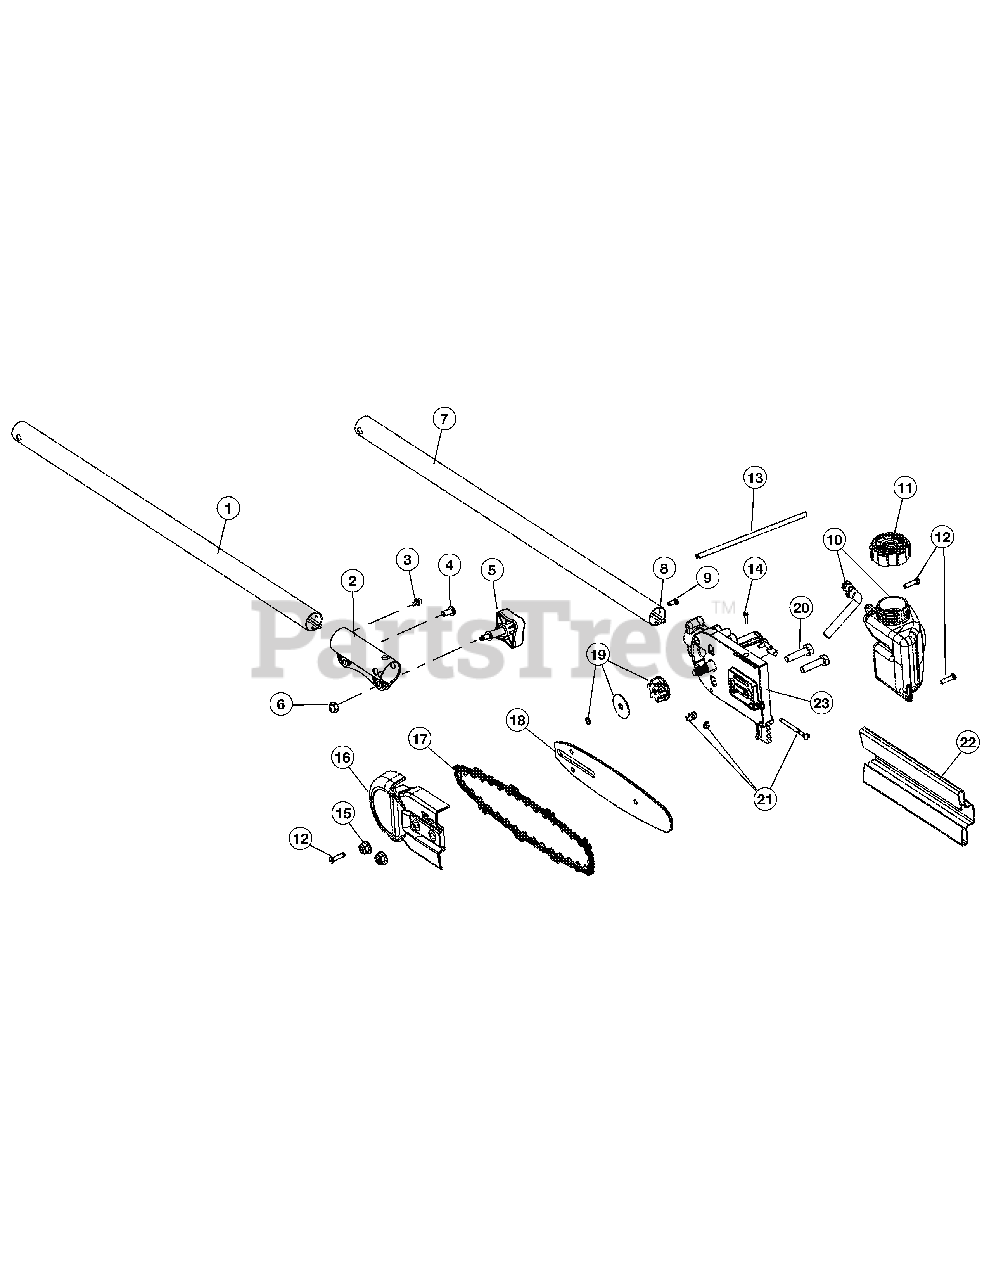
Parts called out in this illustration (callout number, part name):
1	Extension Boom
2	Split Boom Coupler (includes 3-6)
5	Adjustment Knob
6	Knob Retaining Nut
7	Drive Shaft Housing Assembly (includes 8)
8	Flexible Drive Shaft
9	Screw
10	Oil Tank Assembly
11	Fuel Cap Assembly
12	Screw
14	Screw
15	Nut
16	Chain Guard
19	Sprocket Assembly
20	Bolt
21	Chain Tension Hardware Assembly
22	Chain Cover
23	Gearbox Assembly (includes 14 & 19)
